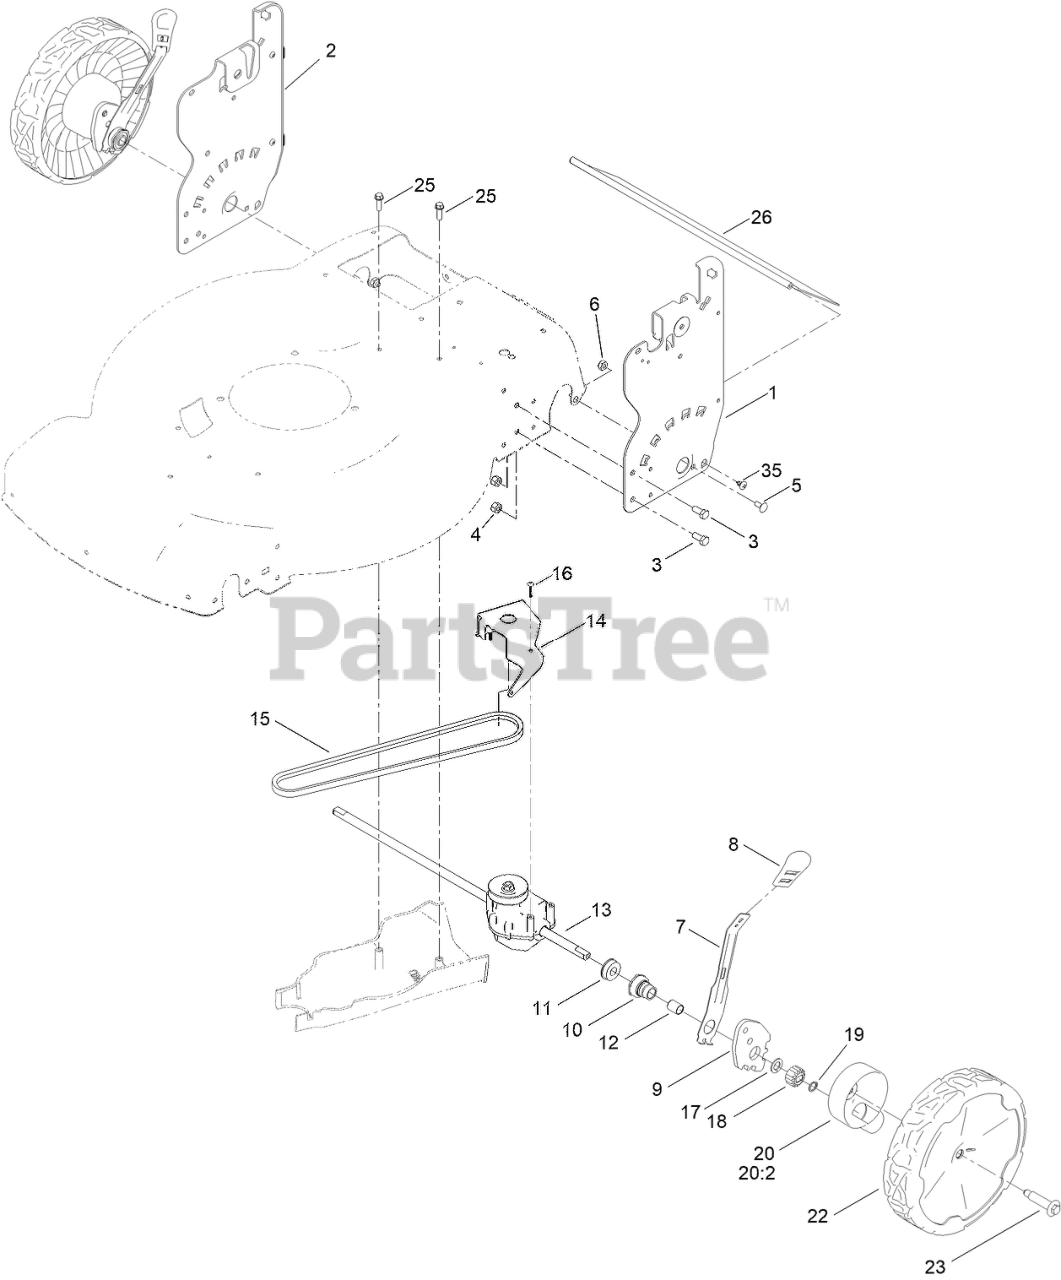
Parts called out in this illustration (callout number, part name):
1	PLATE-HOC, LH (ISO)
2	PLATE-HOC, RH (ISO)
3	SCREW-HH
4	NUT-HEX
5	BOLT-CARR
6	NUT-LOCK
7	ARM-SPRING
8	KNOB-HOC
9	ARM-PIVOT, REAR
10	RETAINER-BUSHING, HOC
11	BEARING-BALL
12	BUSHING-SLEEVE
13	TRANSMISSION-RWD
14	BRACKET-TRANSMISSION
15	V-BELT
16	SCREW-PLASTITE
17	WASHER-THRUST
18	GEAR-PINION, 15T
19	RING-RETAINING
20	ASM-COVER, GEAR (DK GRAY)
20:2	WASHER-STEPPED
22	ASM-9.65" WHEEL, GEARED
23	WHEEL BOLT
25	SCREW-PLASTITE, HWH
26	SHIELD-TRAILING
35	SCREW-THD
